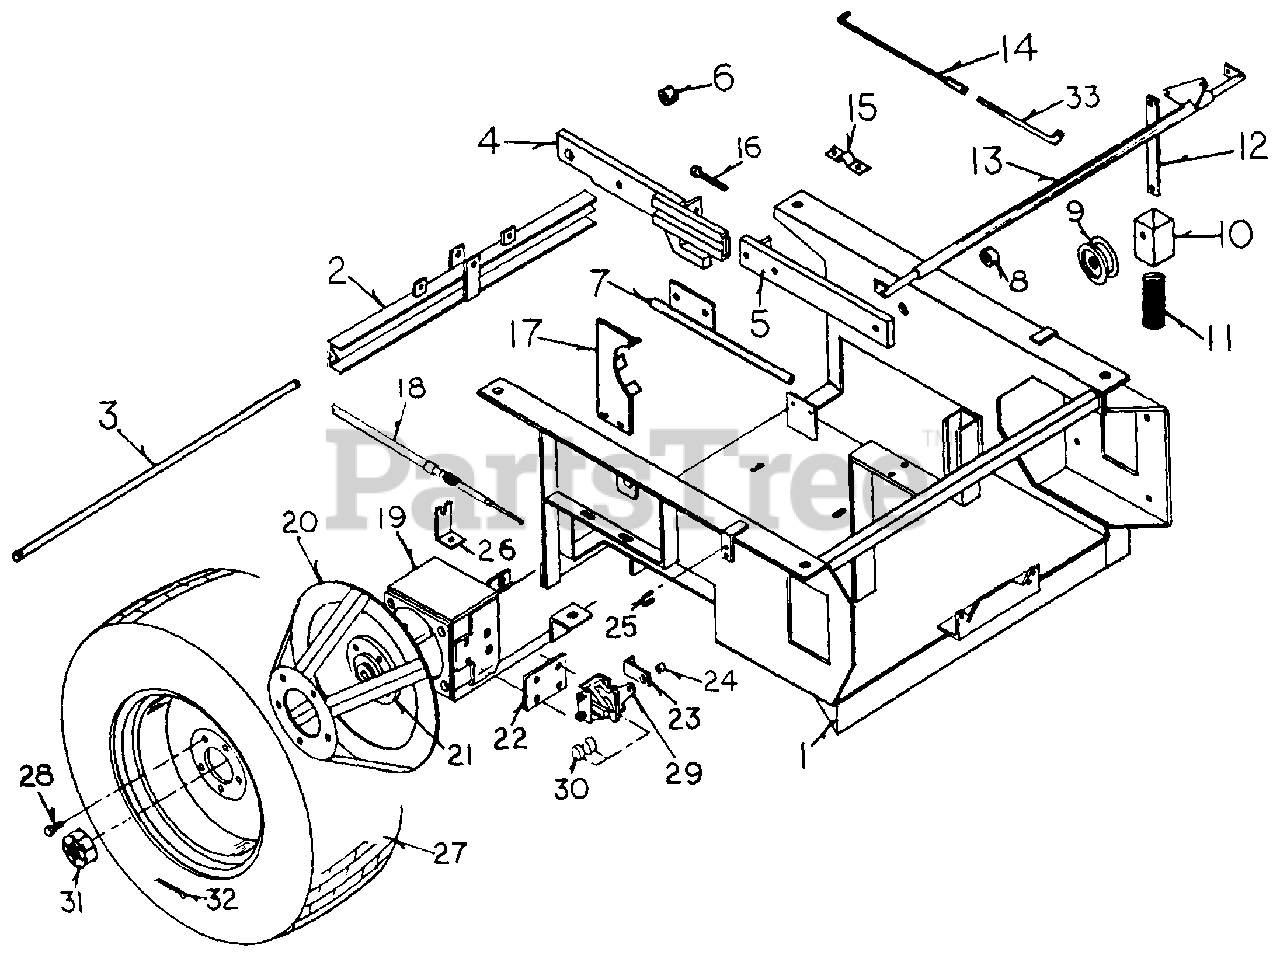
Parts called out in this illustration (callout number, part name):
1	Base
2	Lift Bar
3	Cross Bar Pin
4	Deck Lift Arm, Front Adjustable
5	Deck Lift Arm, Back
6	Bushing, Long
8	Bushing, Short
10	Spring Loaded Idler Mount
12	Pivot Bar Linkage
13	Brake Clutch Rod
14	Brake Rod, Adjustable
15	Cross Rod Bearing
16	Deck Arm Adjusting Bolt
19	Axle
21	5 Bolt Hub
22	Brake Caliper Mount
23	Cable End
24	Bushing
25	Clamp
26	Cable Dead Head
27	Tire Assembly, 20 x 8.00-10
27	Tire Assembly, 20 x 10.00-10
29	Brake Caliper, LH
32	Cotter Key
